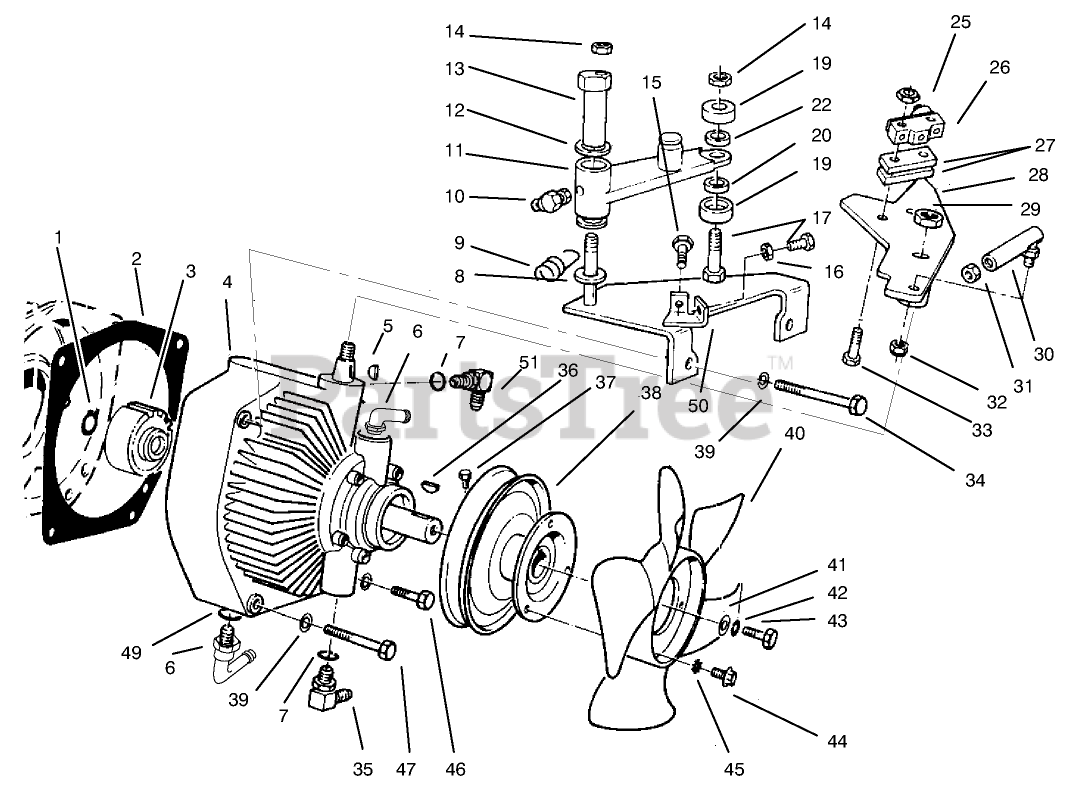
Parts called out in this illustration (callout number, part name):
1	RING-SNAP, EXTERNAL
2	TRANS GASKET
3	GEAR-SPUR
4	TRANSMISSION - HYDRO
5	KEY-WOODRUFF
6	ADAPTER
7	O-RING
8	WASHER-FLAT
9	SPRING-EXTENSION
10	FITTING-GREASE
11	NEUTRAL SWITCH ARM ASSY
12	WASHER-THRUST
13	STUD-TRACTION
14	NUT-LOCK, NI
15	SCREW-HH
16	NUT-HEX
17	SCREW-HH
19	BEARING-BALL
20	SPACER
22	SPACER-BEARING
25	NUT-HEX
26	SWITCH-MICRO
27	PLATE-SWITCH
28	Lever-Traction
29	NUT-LOCK, NI
30	JOINT-BALL
31	NUT-JAM
32	NUT-LOCK
33	SCREW-PPH
34	SCREW-HH
35	Fitting-Hydraulic 90deg. (Incl. Ref. #7)
36	KEY-WOODRUFF
37	SCREW-SQH
38	TRANS PULLEY
39	WASHER-LOCK
40	FAN 8"
41	WASHER-FLAT
42	WASHER-LOCK
43	SCREW-HH
44	SCREW-SHWH
45	WASHER-LOCK/EXT
46	SCREW-HH
47	SCREW-HH
49	O-RING
50	Plate-Traction
51	FITTING-ELBOW-90 DEG
